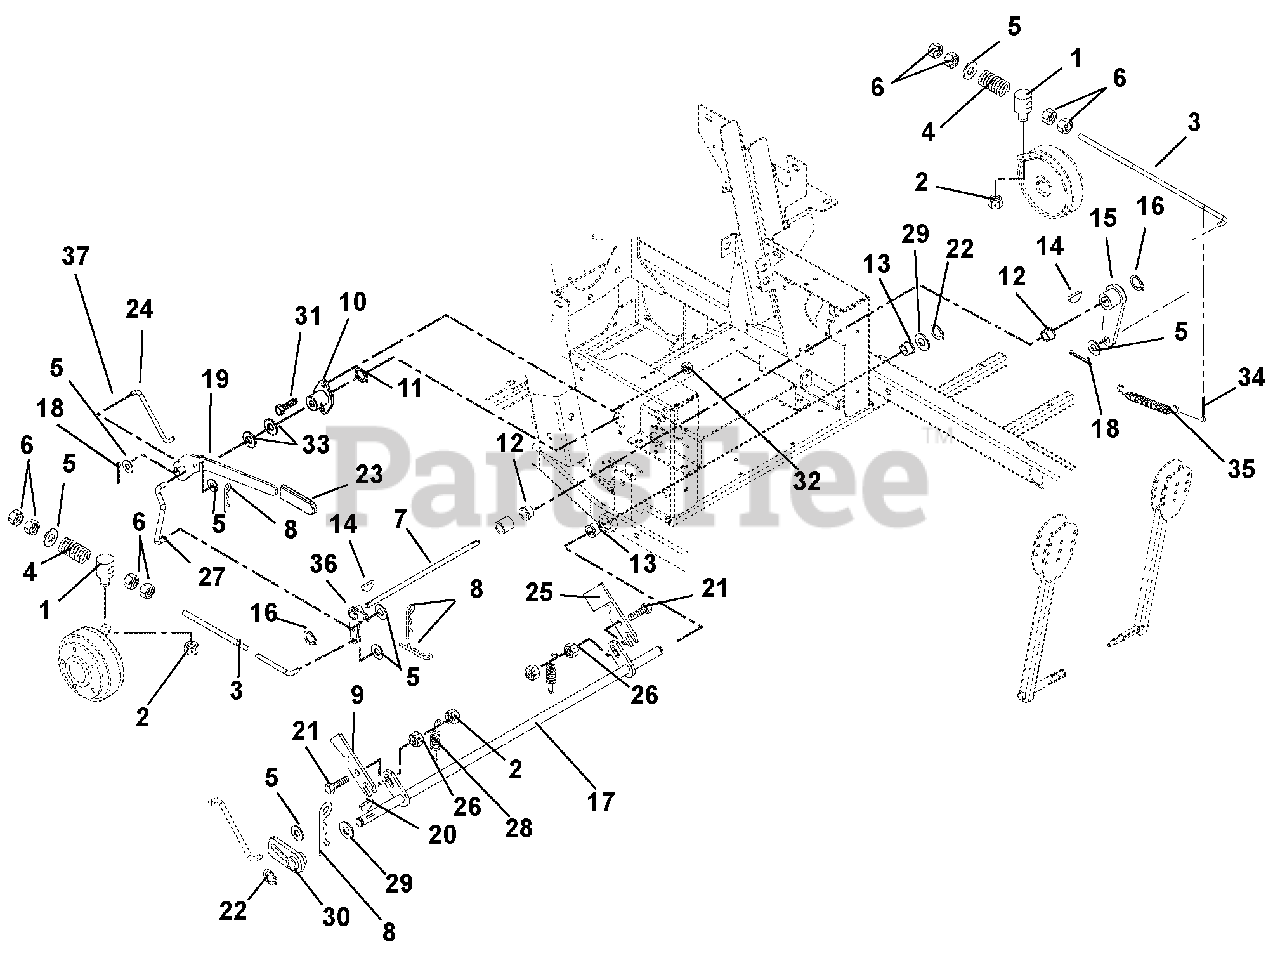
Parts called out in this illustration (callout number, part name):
1	Pivot, Brake Rod
2	Nut, Locking Center .31-18
3	PTO Link Rod (992316, 317, 321, 322)
4	Spring, Compression .142 x .710 x 1.75
5	Washer, Flat Steel .406 x .812 x .065
6	Nut, Hex .38-16
7	Shaft, Brake Cross
8	Pin, Hair
9	Slide, Interlocking Brake
10	Bushing, Flange
11	Ring, Retaining External .625 x .05
12	Bushing, Flange Nylon .762 x 1.00 x .58 x 1.48
13	Bushing, Flange .515 x .75 x .745 x 1.00
14	Key, Woodruff .19 x 1.00 x .19 SAE 8630
15	Arm, Brake
16	Ring, Retaining External .69 x .077
17	Weldment, Mechanical Brake
18	Pin, Cotter External .09 x .75
19	Weldment, Handle
20	Key, Woodruff .13 x .63
21	Bolt, Round Head Square Neck .31-18 x 1.25 Grade 5
22	Ring, Retaining External .50 x .05
23	Grip, Handle
24	Linkage, Brake Actuating
25	Interlock, Safety Switch
26	Nut, Locking Top Flange .31-18
27	Linkage, Brake Actuating
28	Spring, Tension .048 x .44 x 1.75
29	Washer, Flat Steel .505 x 1.00 x .062
30	Weldment, Parking Brake Hub
31	Bolt, Hex .31-18 x .75 Grade 5
32	Nut, Locking Top Flange .31-18
33	Washer, Flat Steel .630 x 1.25 x .062
34	Pin, Cotter .12 x .75 Extended Prong Square Cut
35	Spring, Extension
36	Weldment, 200 Brake ACT. Arm
37	Bushing, Sleeve .377 x .624 x .235
